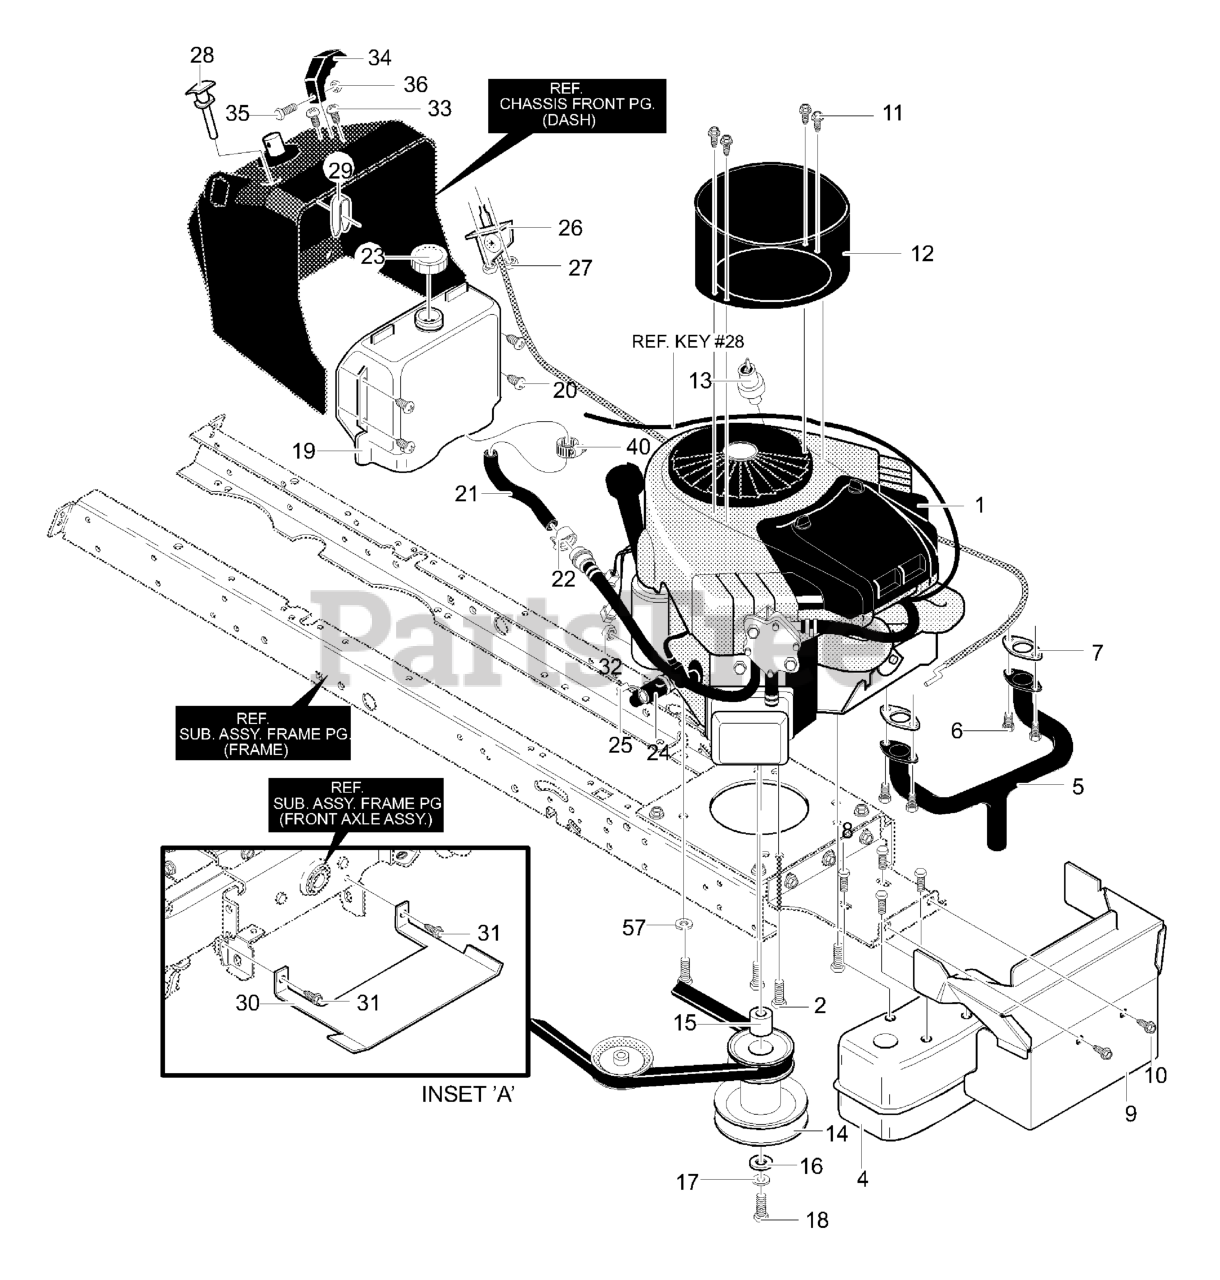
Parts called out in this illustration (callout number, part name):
1	18HP Engine
2	Screw, 3/8-16 x 1.25
4	Muffler, Twin Cyclinder
5	Exhaust Tube
6	Screw (B/S #94755)
7	B/S Exhaust Gasket
8	Screw, 1/4-20x.63
9	Weld, Assy. Shield
10	Screw, 5/16-18 x 0.75
11	Screw, #8-16x.38
12	Plenum
13	Oil Sensor
14	Stack Pulley Assy.
15	Spacer, Sleeve
16	Flatwasher
17	Washer, Regsptlk
18	Bolt, 7/16-20x1.75
19	Fuel Tank 2 Gal.
20	Screw, #12x.50
21	Tubing, Gas Line 14 Inches
22	Clamp, Fuel Line Yellow
23	Gas Cap 2.0 Throat
24	Oil Drain Valve Assembly
25	Cap, Oil Drain Valve Assy.
26	Throttle Control
27	Nut, #10-24 Hxhdnylk
28	Choke
29	Clip, Choke Control
30	Shield, Anti-Dehydration
31	Screw, 5/16-18 x 0.75
32	Nut, 1/4-20 Reghexjam
33	Screw, 10-24x.63
34	Knob, Throttle Control
35	Screw, #8-32x.38
36	Nut, #8-32 Reghex
40	Clamp, Hose Screw Type
57	Washer, Exlk
